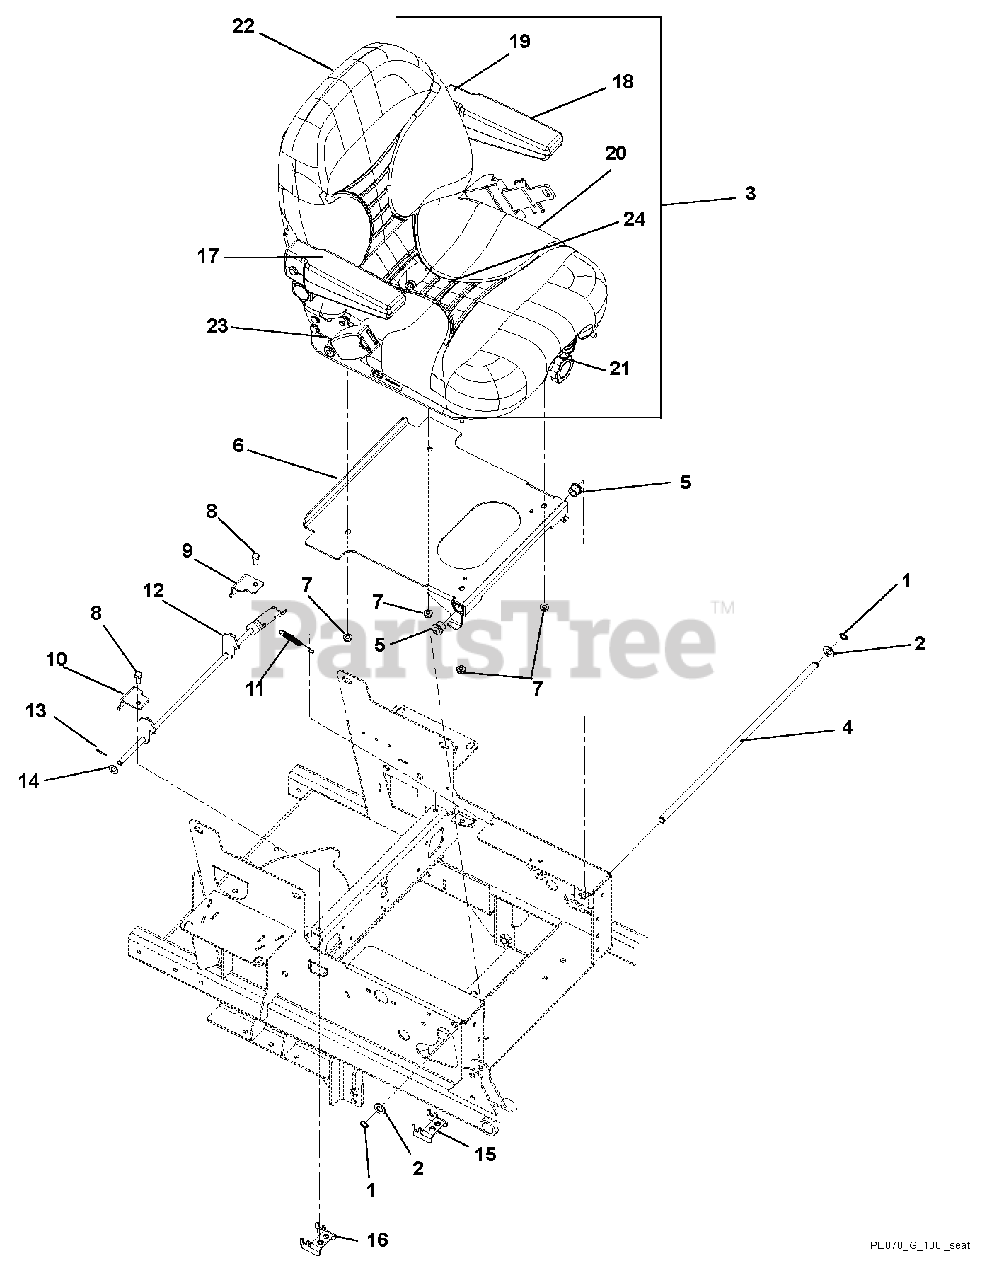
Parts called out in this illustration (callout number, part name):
1	Ring, Retaining External .500 x .050
2	Washer, Flat Steel .531 x 1.00 x .063
3	Seat, Suspension – with Belt, Light Gray
4	Shaft, 100I Seat Pivot
5	Bushing, Flange .516 x .750 x .625 x .937
6	Seat Plate Weldment
7	Nut, Locking Top Flange .31-18
8	Bolt, Hex .31-18 x .75
9	Pro-Turn 100 Left Hand Top Seat Latch Mount
10	Pro-Turn 100 Right Hand Top Seat Latch Mount
11	Spring, Tension .043 x .44 x 3.31
12	Pro-Turn 100 Seat Latch Weldment
13	Pin, Center .09 x .75 Extended Prong Square Cut
14	Washer, Flat Steel .406 x .812 x .065
15	Pro-Turn 100 Seat Latch Mount Weldment Right Hand
16	Pro-Turn 100 Seat Latch Mount Weldment Left Hand
17	Kit, Armrest Assembly Right Hand
18	Kit, Armrest Assembly Left Hand
19	Kit, Back Cushion, Light Grey
20	Kit, Seat Cushion, Light Grey
21	Kit, Seat Knobs
22	Kit, Seat Back
23	Kit, Seat Slides
24	Kit, Seat Spring and Saddle
